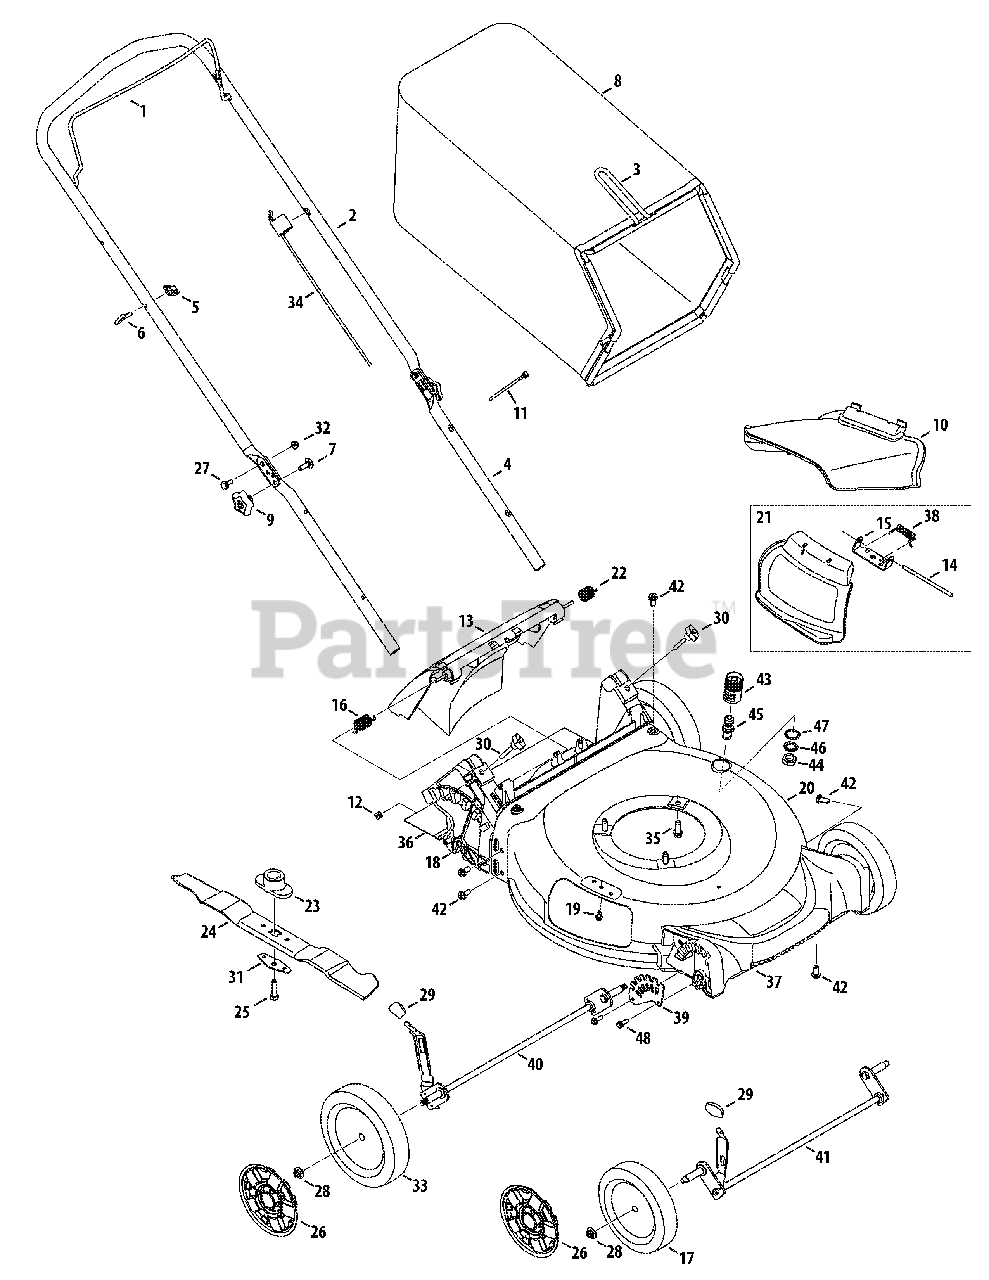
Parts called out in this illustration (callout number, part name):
1	Blade Control
2	Upper Handle
3	Grass Catcher Frame
4	Lower Handle
5	Wing Nut
6	Rope Guide
7	Carriage Screw ,5/16-18
8	Grass Bag
9	Hand Knob
10	Side Chute
11	Cable Tie
12	Nut, Sq., 1/4-20
13	Rear Discharge Door Assembly
14	Hinge Pin
15	Chute Deflector Bracket
16	Torsion Spring - RH
17	Wheel, 7 x 2
18	Rear Baffle
19	Screw, 1/4-20 x .500
20	Deck - 21"
21	Hinged Mulch Plug Assembly
22	Torsion Spring - LH
23	Blade Adapter
24	Mulching Blade
25	Screw , 3/8-24 x 1.50
26	Hub Cap - Front
26	Hub Cap - Rear
27	Sldr. Screw, .375 x .126 x 1/4-20
28	Flange Lock Nut, 3/8-16
29	Adjustment Lever Knob
30	Wing Nut
31	Blade Bell Support
32	Nut, Flange Lock, 1/4-20
33	Wheel, 8 x 2
34	Control Cable
35	TT Sems Screw, 3/8-16 x 1.0
36	Trail shield
37	Front Cover
38	Torsion Spring
39	Front Height Adjuster Plate
40	Rear Axle Assembly
41	Front Axle Assembly
42	Screw, 5/16-14 x .750
43	Water Nozzle
44	Nut, Hex, M16-1.5
45	Water Nozzle Adapter
46	Washer, Lock, 5/8
47	Washer, Flat, .865 x 1.145 x .030
48	Screw, 1/4-15 x .750
